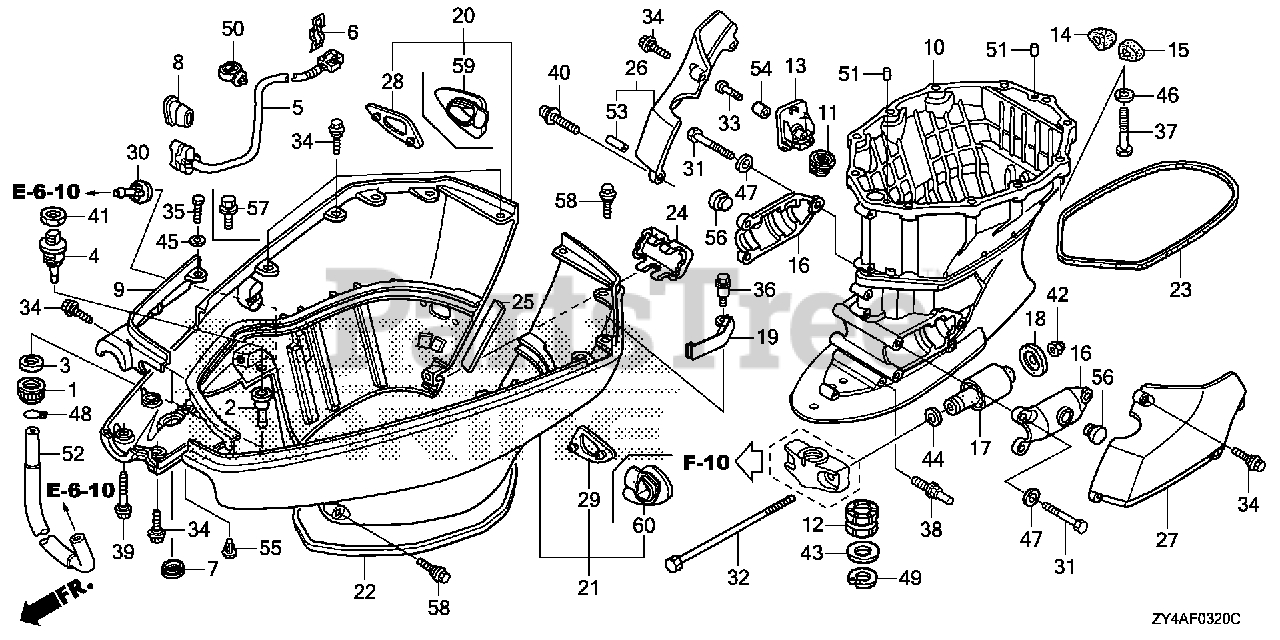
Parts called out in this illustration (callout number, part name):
1	NUT, WATER MOUTH
2	JOINT, WATER HOSE
3	SEAT, WATER MOUTH
4	CAP, WATER JOINT
5	SWITCH ASSY., POWER TILT
6	STAY, POWER TILT SWITCH
7	GROMMET, CASE (LOWER) (C)
8	GROMMET, POWER TILT SWITCH
9	COVER, FR. SEPARATE *NHB14M* (AQUA MARINE SILVER METALLIC)
10	CASE, EXTENSION *NHB14M* (AQUA MARINE SILVER METALLIC)
11	RUBBER, DRAIN PLUG
12	BUSH, VERTICAL SHAFT
13	COVER, DRAIN PLUG *NHB14M* (XL) (AQUA MARINE SILVER METALLIC)
16	HOUSING, MOUNTING (LOWER)
17	MOUNT, RUBBER (LOWER)
18	STOPPER, MOUNT (LOWER)
19	COVER, PLUG MAINTENANCE
20	COVER, R. ENGINE (LOWER) *NHB14M* (AQUA MARINE SILVER METALLIC)
21	COVER, L. ENGINE (LOWER) *NHB14M* (AQUA MARINE SILVER METALLIC)
22	SEAL A, COVER (LOWER)
23	SEAL B, COVER (LOWER)
24	CAP, COVER (LOWER) *NHB14M* (AQUA MARINE SILVER METALLIC)
25	SEAL C, COVER (LOWER)
26	COVER, R. MOUNTING (LOWER) *NHB14M* (XL) (AQUA MARINE SILVER METALLIC)
27	COVER, L. MOUNTING (LOWER) *NHB14M* (XL) (AQUA MARINE SILVER METALLIC)
28	GROMMET, R. IDLE PORT
29	GROMMET, L. IDLE PORT
30	GROMMET, WATER CHECK
31	BOLT, HEX. (10X35)
32	BOLT, HEX. (14X180)
33	SCREW, SPECIAL (6X35)
34	BOLT, SPECIAL (6X17)
35	BOLT, HEX. (6X25)
36	BOLT, SPECIAL (6X22)
37	BOLT, HEX. (12X50)
38	BOLT, SPECIAL (6X12)
39	BOLT, SPECIAL (6X37)
40	SCREW, PAN (6X25)
41	NUT, HEX. (16MM)
42	NUT, SELF-LOCK (14MM)
43	WASHER (30MM)
44	WASHER, PLAIN (14MM)
45	WASHER (6MM)
46	WASHER, PLAIN (12MM)
47	WASHER, PLAIN (10MM)
48	CLIP, TUBE (B12.5)
49	CIRCLIP (INNER) (43)
50	CLIP, WIRE HARNESS (25MM)
51	PIN, DOWEL (6X10)
52	TUBE, WATER JOINT
53	COLLAR, DISTANCE (6.5X9X11.5)
54	COLLAR, DISTANCE (6X10.5X25)
55	PLUG, HOLE (5MM)
56	RUBBER C, STAND STOPPER
57	BOLT-WASHER (6X25)
58	BOLT, SPECIAL (6X17)
